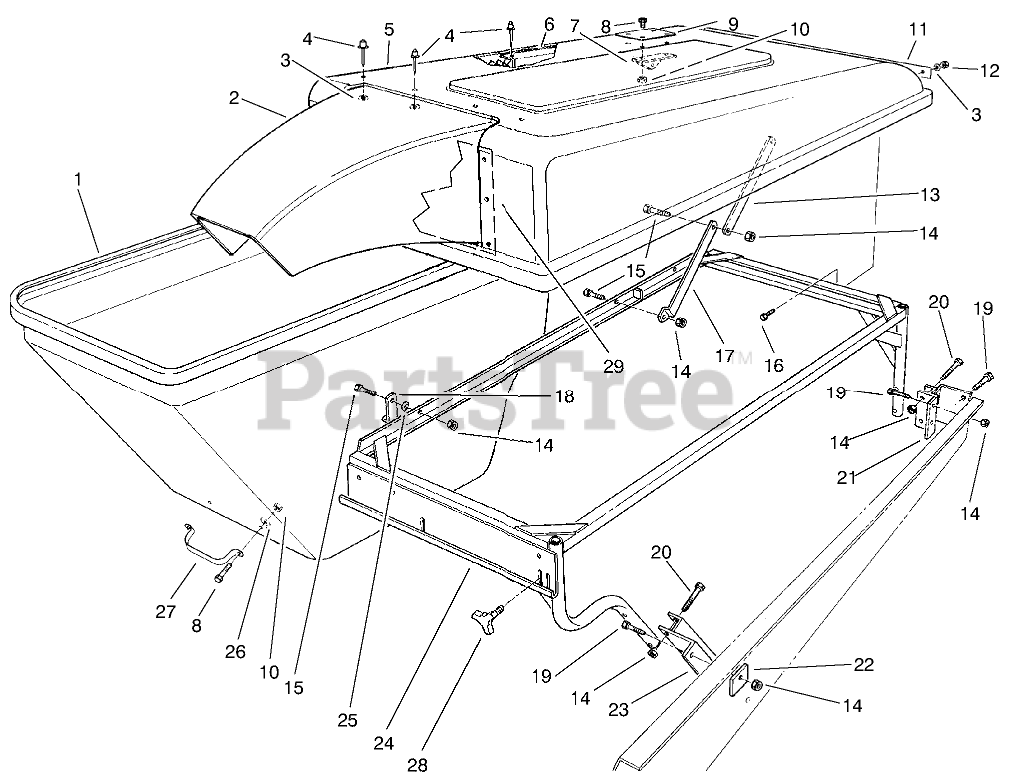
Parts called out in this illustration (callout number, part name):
1	BAGGER HOPPER
2	BAGGER SNOUT
3	WASHER-FLAT
4	NUT-LOCK
5	HOOD-GRASS CATCH
6	Bagger Screen
7	Pivot
8	SCREW-HH
9	HOOD PLATE
10	NUT-LOCK, NI
11	HINGE PLATE
12	NUT-LOCK, NI
13	Link
14	NUT-LOCK, NI
15	SCREW-HH
17	Link-Bag
18	Latch-Hopper
19	SCREW-HH
20	SCREW-HH
21	Bracket-Rear
22	Plate-Reinforcing
23	Bracket-Front
24	HOPPER FRAME WA
25	WASHER-SPRING
26	WASHER-FLAT
27	Handle
29	NUT-LOCK, NI
